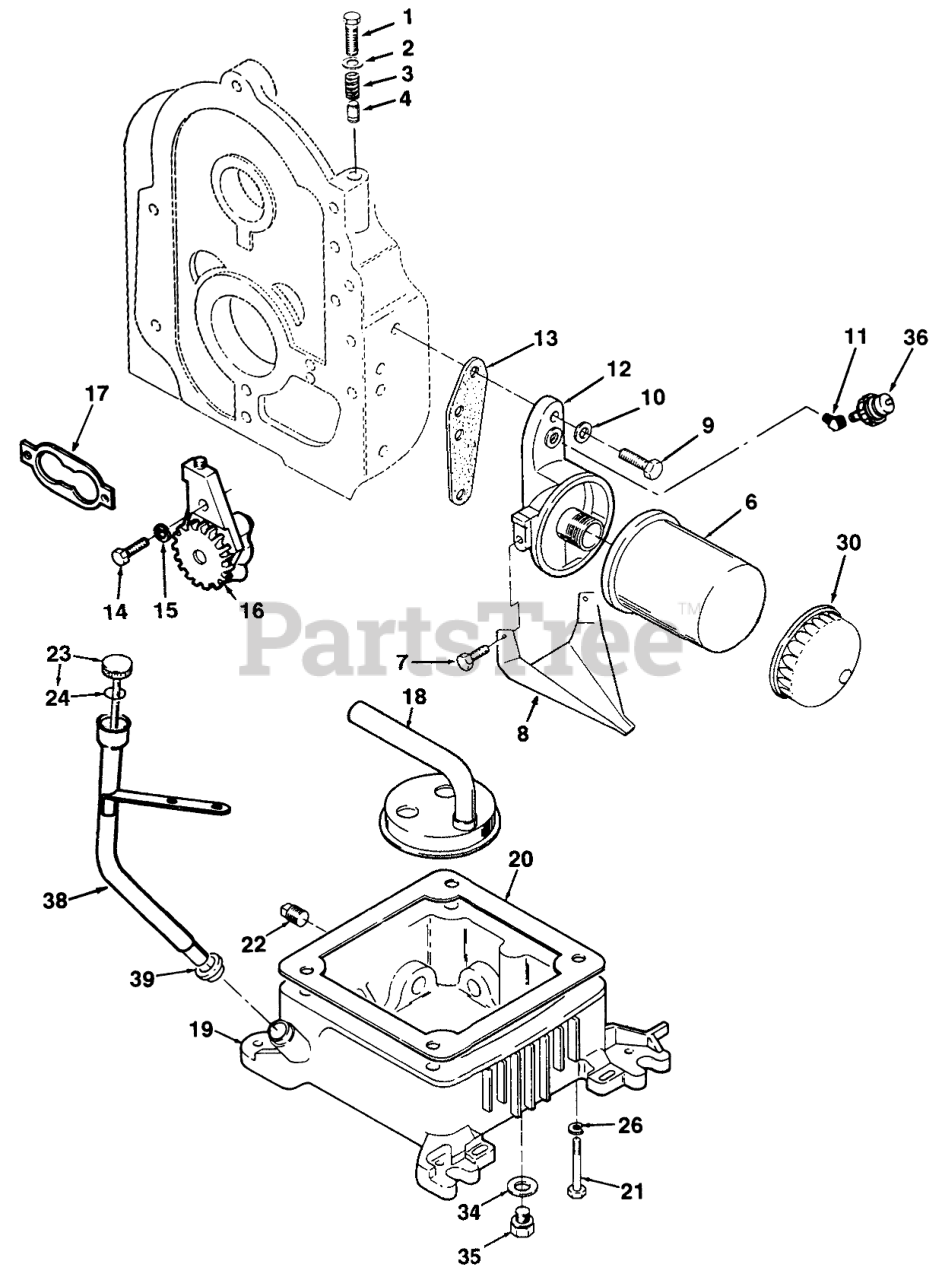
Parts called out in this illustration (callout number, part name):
1	Bolt
2	WASHER
3	Spring
4	Piunger
6	OIL FILTER
7	SCREW-HH
8	DRAIN-OIL FILTER
9	HHCS 5/16-18 X 1
10	WASHER
11	ELBOW-45 DEG
12	ADAPTER-OIL FILTER
13	GASKET-OIL FILTER ADAPT
14	SCREW - CAP HEX HEAD
15	WASHER-LOCK, SPRING
16	Oil Pump
17	Oil Pump Gasket Kit
18	CUP-INTAKE, OIL PUMP
19	Oil Base (Includes all plugs and plug gasket)
20	GASKET
21	Screw
22	PLUG - SQUARE HEAD
23	Oil Fill Cap and Indicator (Includes "O" Ring)
24	SEAL 0-RING
26	WASHER-FLAT
30	Oil Filter Wrench
34	GASKET
35	PLUG-OIL
36	OIL-PRESSURE SWITCH
38	Oil Fill Tube
39	SEAL-OIL FILL TUBE
